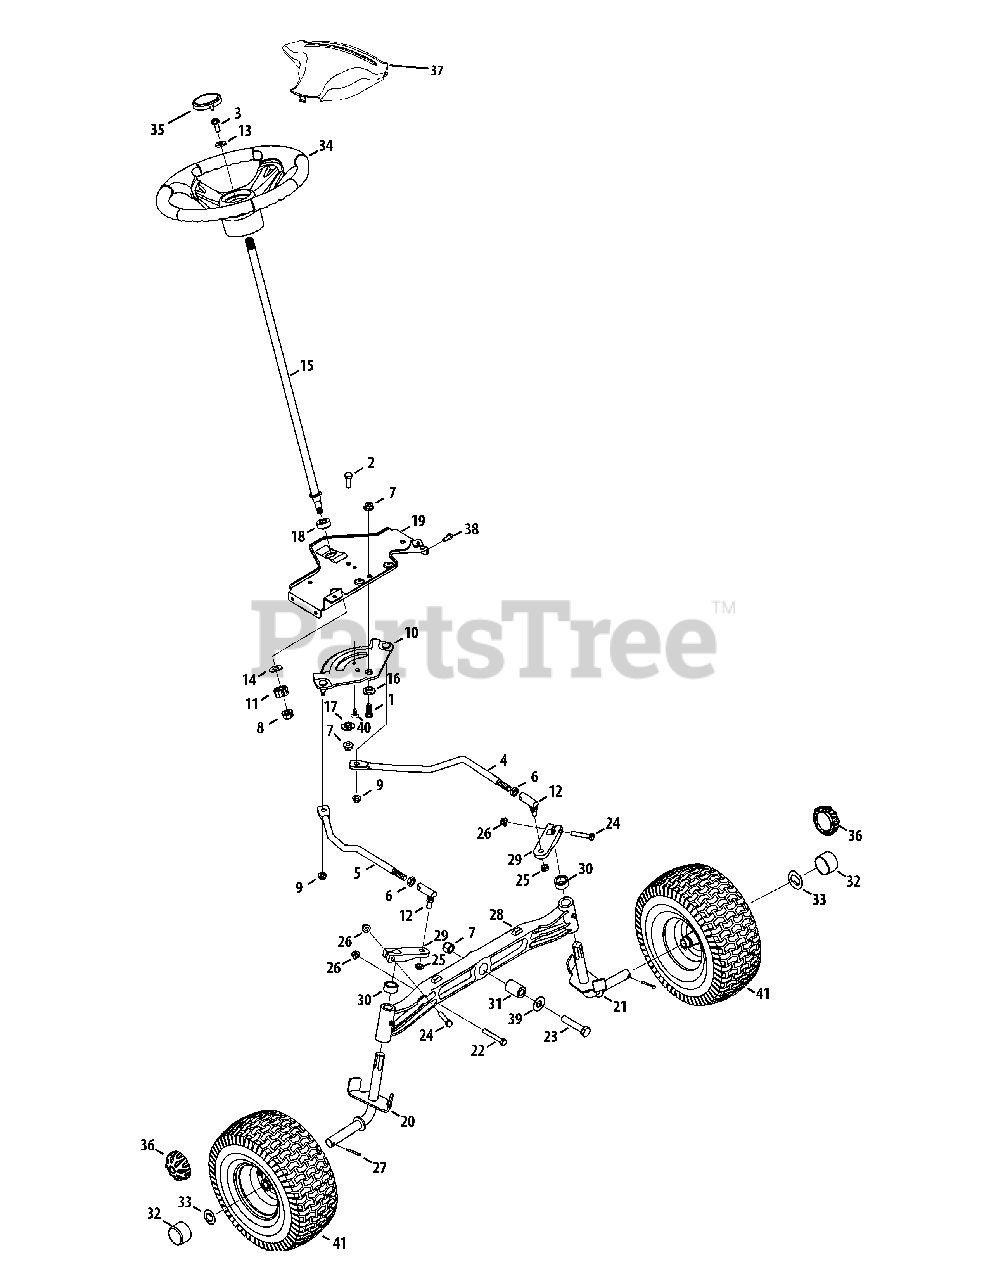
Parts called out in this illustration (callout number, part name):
1	Screw, 3/8-16 x 1.0
2	Hex Screw 3/16 x 1.00
3	Hex Screw 5/16-18 x 1.00 Special
4	Link, Drag LH
5	Link, Drag RH
6	Hex Jam Nut 7/16-20
7	Flange Lock-Nut 3/8-16 Gr. F Nylon
8	Flange Lock Nut, 7/16-20
9	Hex Flange L-Nut 5/16-18
10	Steering Gear, 11/90 Ratio
11	Steering Pinion Gear
12	Ball Joint, 7/16 - 20
13	Flat Washer .406 ID x .875 DE x .105
14	Flat Washer .510 x 1.120 x .060
15	Steering Shaft .625 OD x 24.25
16	Shoulder Spacer .385 x 1.25 x .3025
17	Spacer .38 x 1.375 Special
18	Hex Flange Bearing 5/8
19	Steering Support Bracket
20	Axle Ass’y RH .750 Dia. (42" Deck )
21	Axle Ass’y LH .750 Dia. (42" Deck )
22	Hex Bolt 5/16-18 x 2.25
23	Hex Cap Screw, 3/8-16 x 2.5
24	Hex Screw 5/16-18 x 1.75" Lg.
25	Hex Cent L-Nut 3/8-24
26	Flange Locknut 5/16-18 Gr. F, Nylon
27	Cotter Pin 5/32" Dia.
28	Pivot Bar (cast iron)
29	Steering Block
30	Spacer .710 ID x .125 OD x .56
31	Spacer .385 x 1.0 x 1.5075
32	Hub Cap
33	Flat Washer .350 x 1.559 x .062
34	Steering Wheel, Standard Grip
34	Steering Wheel, Softgrip
35	Steering Wheel Cap (sprig) logo
36	Hub Cap
37	Steering Wheel Cover (w/o sprigs)
38	S-Tapp Scr. 5/16-18 x .75
39	Flat Washer .406 x .875 x .059
40	Rachet Clip
41	See Front and Rear Wheels
